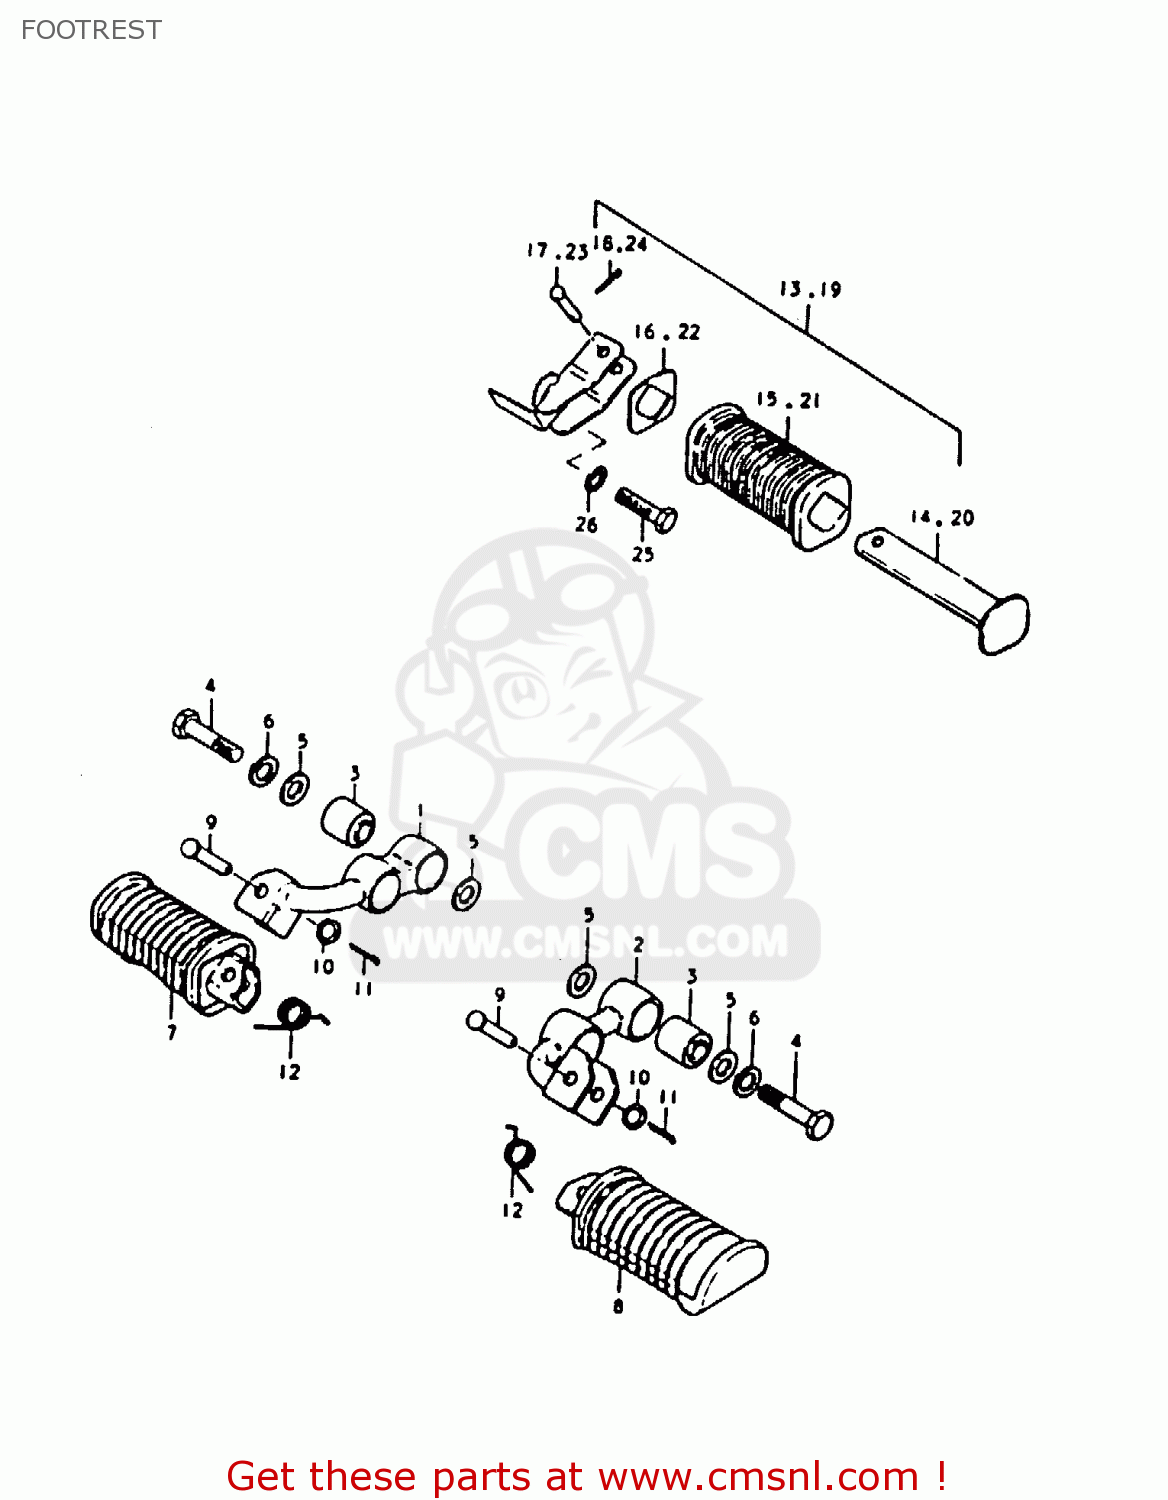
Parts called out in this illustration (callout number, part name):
1	BAR,FRONT FOOTREST
2	BAR,FRONT FOOTREST,LEFT
3	BUSH
4	BOLT
5	WASHER (10.1X21X2.3)
6	LOCK WASHER
7	RUBBER,FRONT FOOTREST
8	FOOTREST
9	PIN
10	WASHER
11	PIN 20X20
12	SPRING
13	FOOTREST ASSEMBLY,REAR
14	BAR,REAR FOOTREST
15	RUBBER,PILLION FOOTREST
16	WASHER,REAR FOOTREST RUBBER
17	PIN
18	PIN
19	FOOTREST ASSEMBLY,PILLION
20	BAR,REAR FOOTREST
21	RUBBER, LH
22	WASHER,REAR FOOTREST RUBBER
23	PIN
24	PIN
25	BOLT 10X30
26	LOCK WASHER
